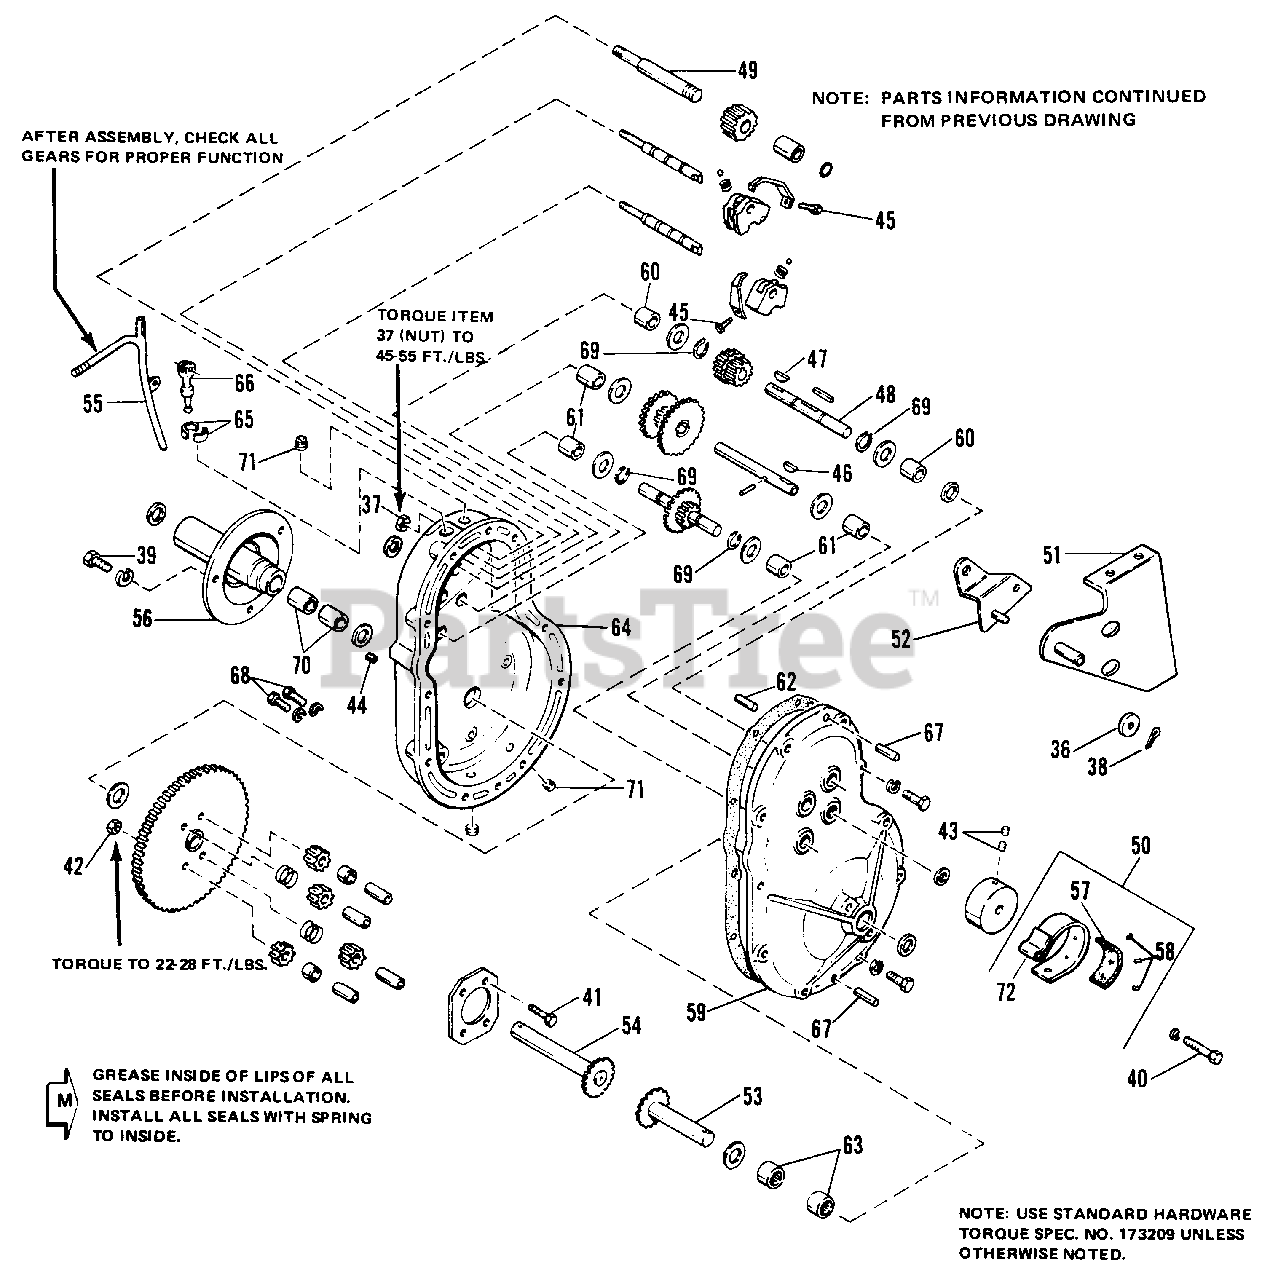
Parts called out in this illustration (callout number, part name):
36	WASHER, Plain 1/4
37	NUT, Hex Full 7/16-14
38	PIN, Cotter 1/8 x 3/4
39	CAPSCREW, Hex 3/8-16 x 7/8
40	CAPSCREW, Hex 5/16-18 x 1-1/2
41	CAPSCREW, Hex 3/8-16 x 2-1/2
42	LOCKNUT, Hex Full 3/8-16
43	SETSCREW, 5/16-18 x 5/16
44	SETSCREW, 3/8-16 x 3/8
45	SCREW, Hex Washer Hd., 5/16-18 x 5/16
47	KEY, 3/16 x 3/4
48	SHAFT, Input
49	SHAFT, Reverse Pinion
50	BRAKE BAND ASSEMBLY
51	TRANSMISSION SUPPORT ASSEMBLY
52	IDLER LEVER ASSEMBLY
53	AXLE ASSEMBLY, LH
54	AXLE ASSEMBLY, RH
55	SHIFT ROD ASSEMBLY
56	HOUSING ASSEMBLY, Axle, W/Bushings
57	LINING, Brake
58	RIVET, No. 7 x 1/4
59	COVER, Gear Case W/Bearings
61	BEARING, Roller
63	BEARING, Roller
64	GEAR CASE, W/Bearinys
66	SHIFT ROD ASSEMBLY
67	PIN, Roll, 3/8 x 1
68	CAPSCREW, Hex, 3/8-16 x 3/4
69	RlNG, Retaining
